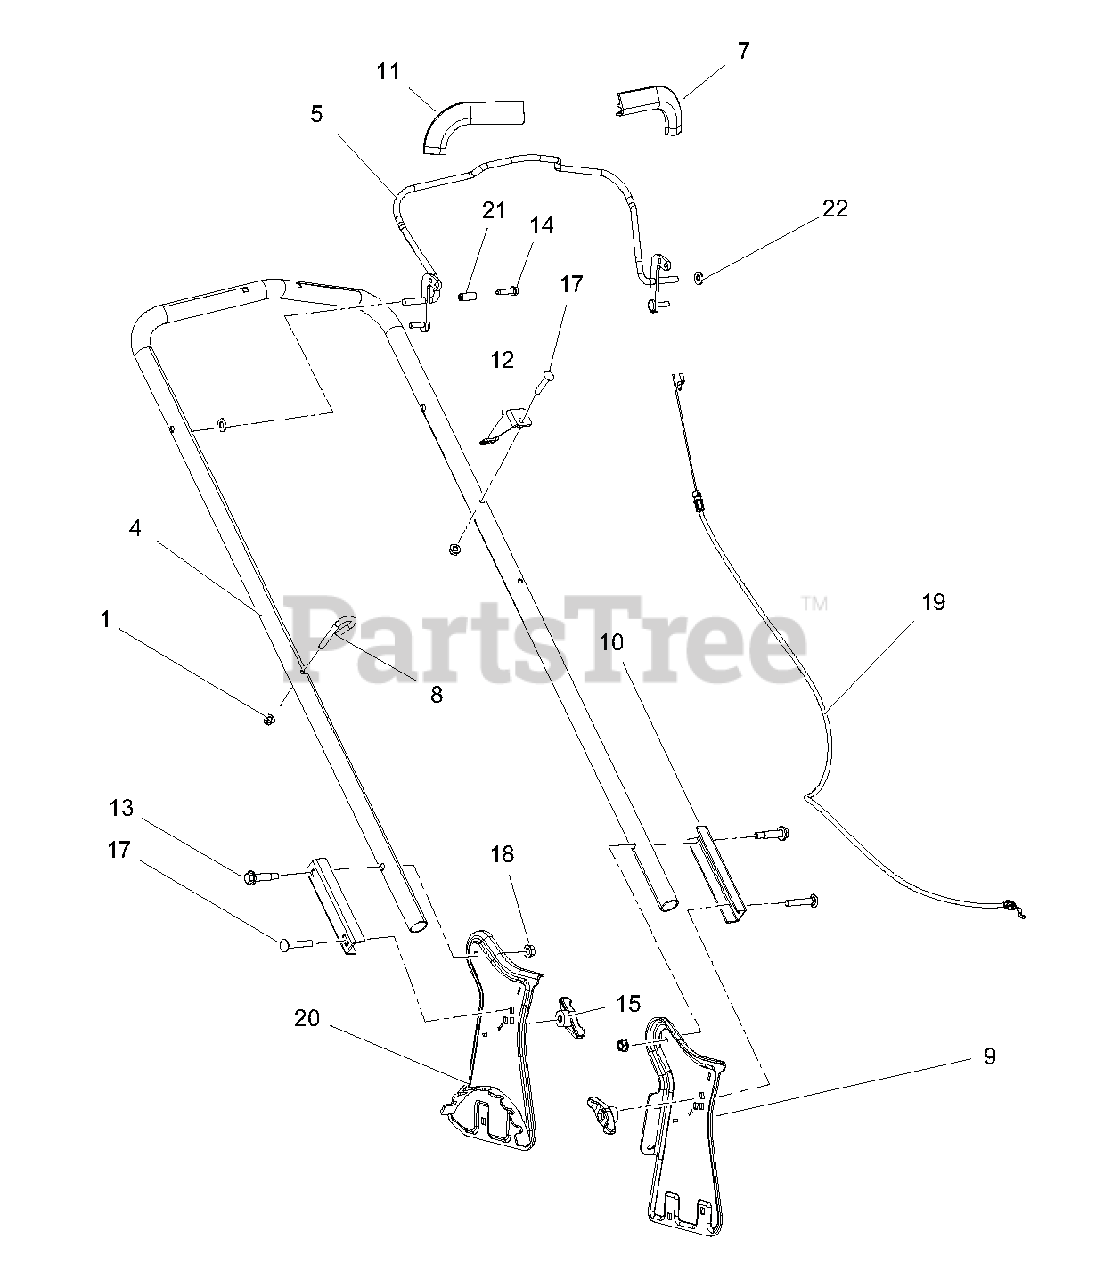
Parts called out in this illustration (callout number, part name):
1	@NUT-LK-TOP-FLG .25-20 YWZC
4	HANDLEBAR, LM
5	WLDMT, OPC BAIL
7	GUARD, FINGER - LH
8	HOLDER, RECOIL CORD
9	SUPPORT, LH HANDLEBAR
10	BRKT, HANDLEBAR FIXED ADJUST
11	GUARD, FINGER - RH
12	BRKT, CABLE ANCHOR - LM PUSH
13	BLT-SHLDR, .50X1.15X.312-18GR5
14	@SCR-TAP .25-20X1.00 HWH TR YZ
15	KNOB,WING .31-18 UNC NYL/TALC
17	@BLT-RDHDSQNK .25-20X1.50 G5YZ
18	@NUT-LK-TOP-FLG .25-20 YWZC
19	CABLE, OPC
20	SUPPORT, RH HANDLBAR
21	CAP, VINYL, .25 ID
22	@WSHR-FL-STL.344X.688X.065YWZC
